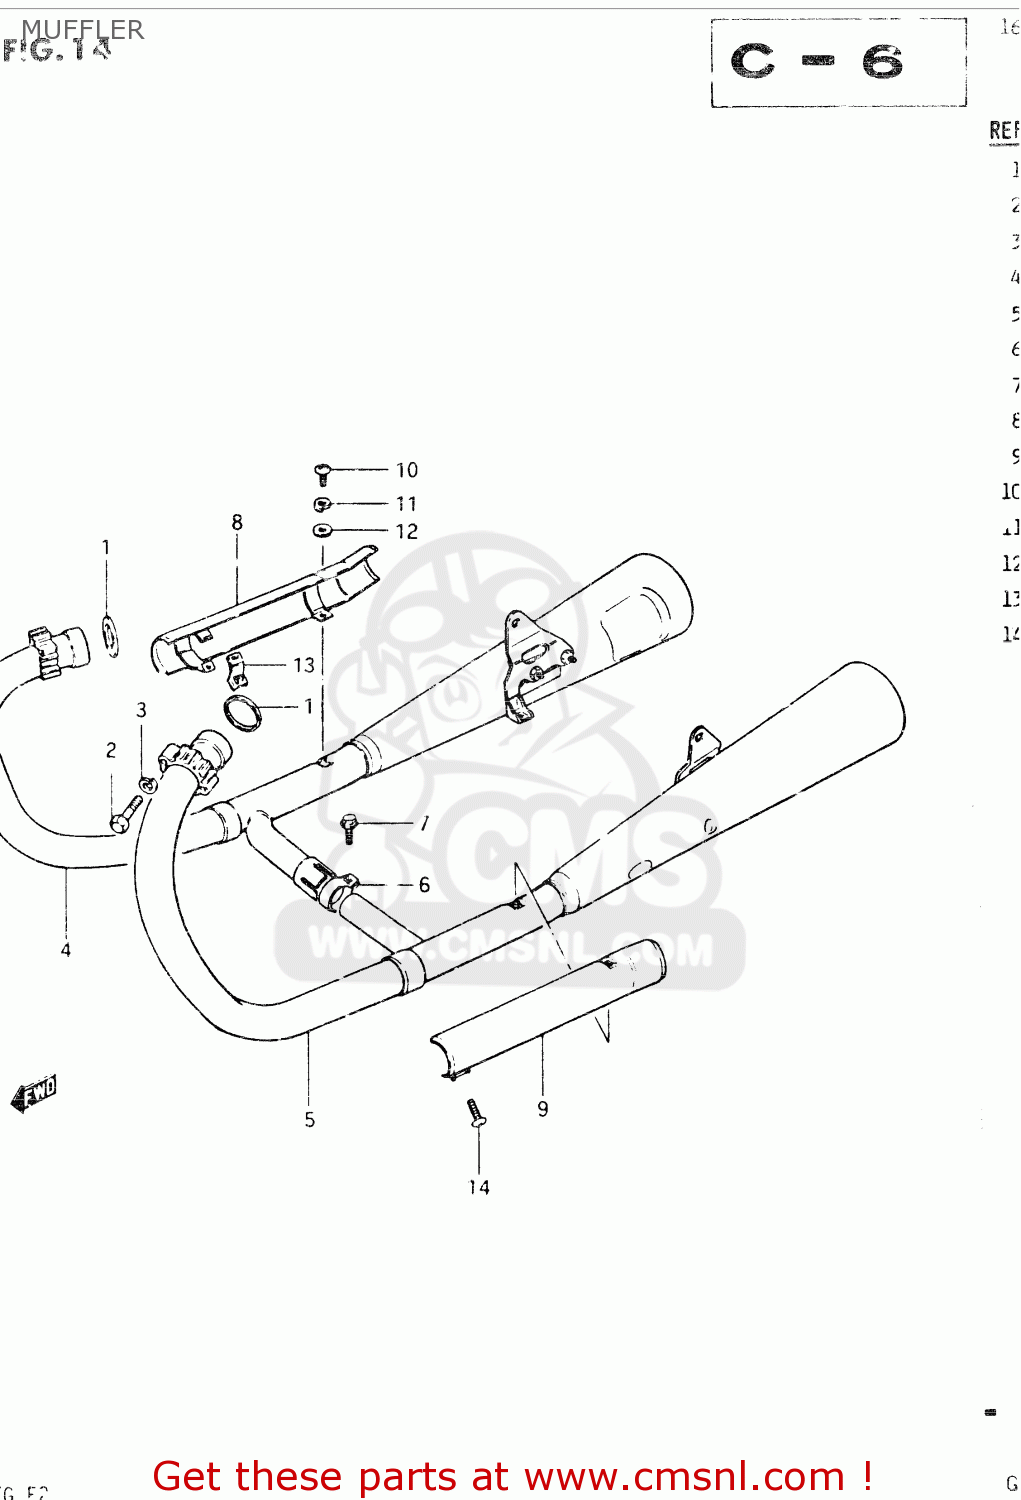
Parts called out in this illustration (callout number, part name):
1	GASKET,EXHAUST PIPE (NAS)
2	BOLT 8X40
3	LOCK WASHER
4	MUFFLER ASSY,R
5	MUFFLER ASSY,L
6	CLAMP
7	BOLT
8	COVER,MUFFLER
9	COVER,MUFFLER
10	SCREW
11	LOCK WASHER
12	WASHER
13	CLAMP,MUFFLER COVER
14	SCREW
